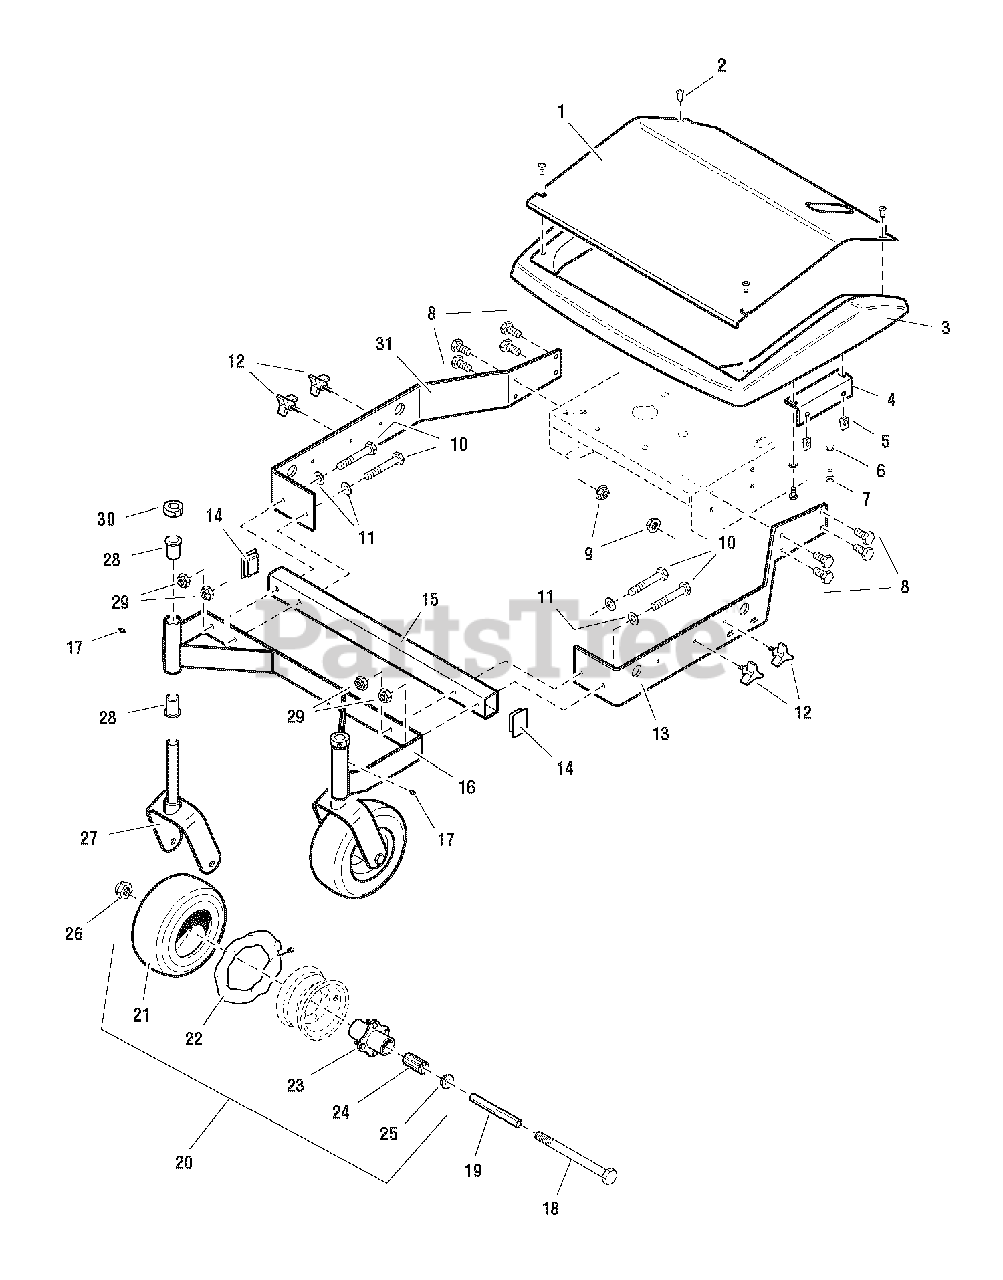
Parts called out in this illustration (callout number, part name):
1	SHIELD INSERT, Complete (includes decals)
2	SCREW, Allen Head, 1/4-20 x 1/2
3	GUARD, Mower Deck
4	SHIELD MOUNT BRACKET
5	BODY CLIP, 5/16-18
6	LOCKWASHER, 1/4
7	CAPSCREW, Hex Head, 1/4-20 x 3/4
8	BOLT, 3/8-16 X 1" GD5 CZ
9	NUT, Hex Serrated Flange, 3/8-16
10	BOLT, 3/8-16 X 2-1/2" GD5 CZ
11	WASHER, 3/8
12	KNOB
13	FRAME RAIL - LH
14	PLASTIC CAP
15	CROSS TUBE
16	CASTER MOUNT FRAME
17	GREASE FITTING, 1/4-28
18	CAPSCREW, Hex Head, 1/2-13 x 5-1/2
19	AXLE, Caster
20	WHEEL & TIRE ASSEMBLY, Silver, 9 x 3.5 x 4, Complete (includes Ref 18 - 22)
21	TIRE, Front, 9 x 3.5 x 4
22	TUBE, for 9 x 3.5 x 4 Tire
23	HUB & BEARING ASSEMBLY, Complete, Silver (includes Ref 21 & 22)
24	BEARING, ROLLER 3/4" ID X 3.25" (ONE PER TIRE)(SV)
25	RETAINER, Bearing (2 per tire)
26	NUT, Hex Nylon Lock, 1/2-13
27	CASTER YOKE
28	BUSHING, Flange
29	NUT, Hex Nylon Lock, 3/8-16
30	COLLAR, Split, 3/4
31	FRAME RAIL - RH
